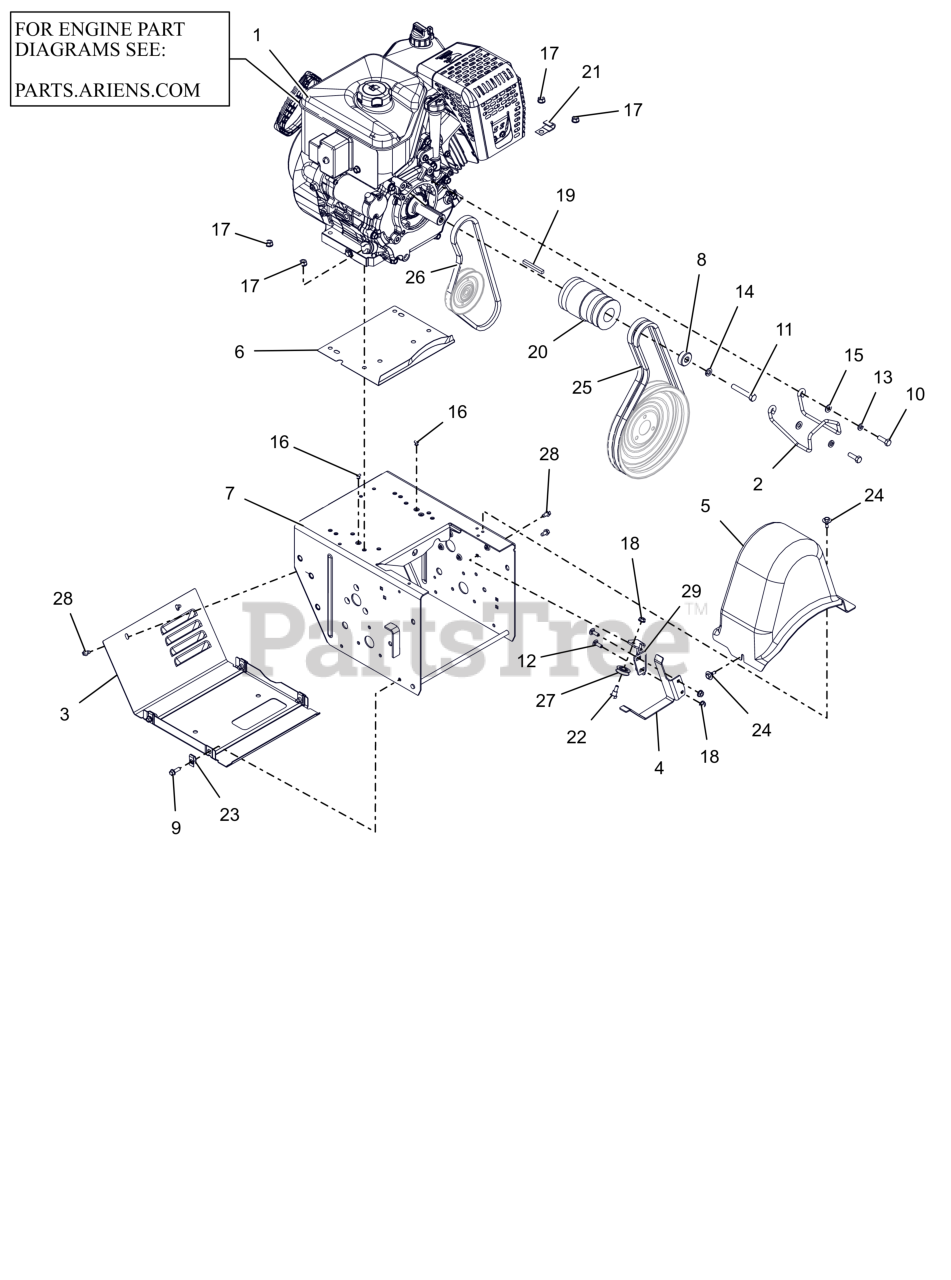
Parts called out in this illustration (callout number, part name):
1	ENGINE, AX420 GEN 3 120V/60W
2	FINGER, BELT
3	COVER, BOTTOM - VENTILATED
4	FINGER, BELT - FLAT
5	COVER, BELT-LARGE
6	BAFFLE, WATER - LARGE BLOCK
7	FRAME, MAIN - PRO (WELDMENT)
8	BSHG, SPCR .406 X 1.250 X .500
9	BLT, HWH .25-20X.75 G5 ZCC
10	BLT, HEX 0.3125-24X1 G5 ZCC
11	BLT, HEX .38-24X2.25 G5 ZCC
12	BLT, RHSN .25-20X.750 G5 ZCC
13	WSHR, LK-HVY .312X.097 ZCC
14	WSHR,LK-REG .375X.094 ZCC
15	WSHR,FLT .344X.688X.065 ZCC
16	RVT, POP .1875 ZCC
17	NUT,LK-CTR-FLG .31-18 GF ZCC
18	NUT-LK-TOP-FLG .250-20 GF ZCC
19	KEY .25X.25X2.25
20	SHEAVE, COMBO HYDRO TRACK 4L
21	J-CLAMP
22	BOLT, SHLDR -.375 X .375 X .25-20
23	NUT-RTNR .25-20X.56
24	SCR-TAP .25-20X.5 CAPTIVE
25	V-BELT, HA-RAW EDGE (SET)
26	V-BELT, 4L-WRAPPED
27	PULLEY, CABLE
28	SCR-TAP .25-20X.50 HWH ZCC
29	BRACKET, CLUTCH CABLE
